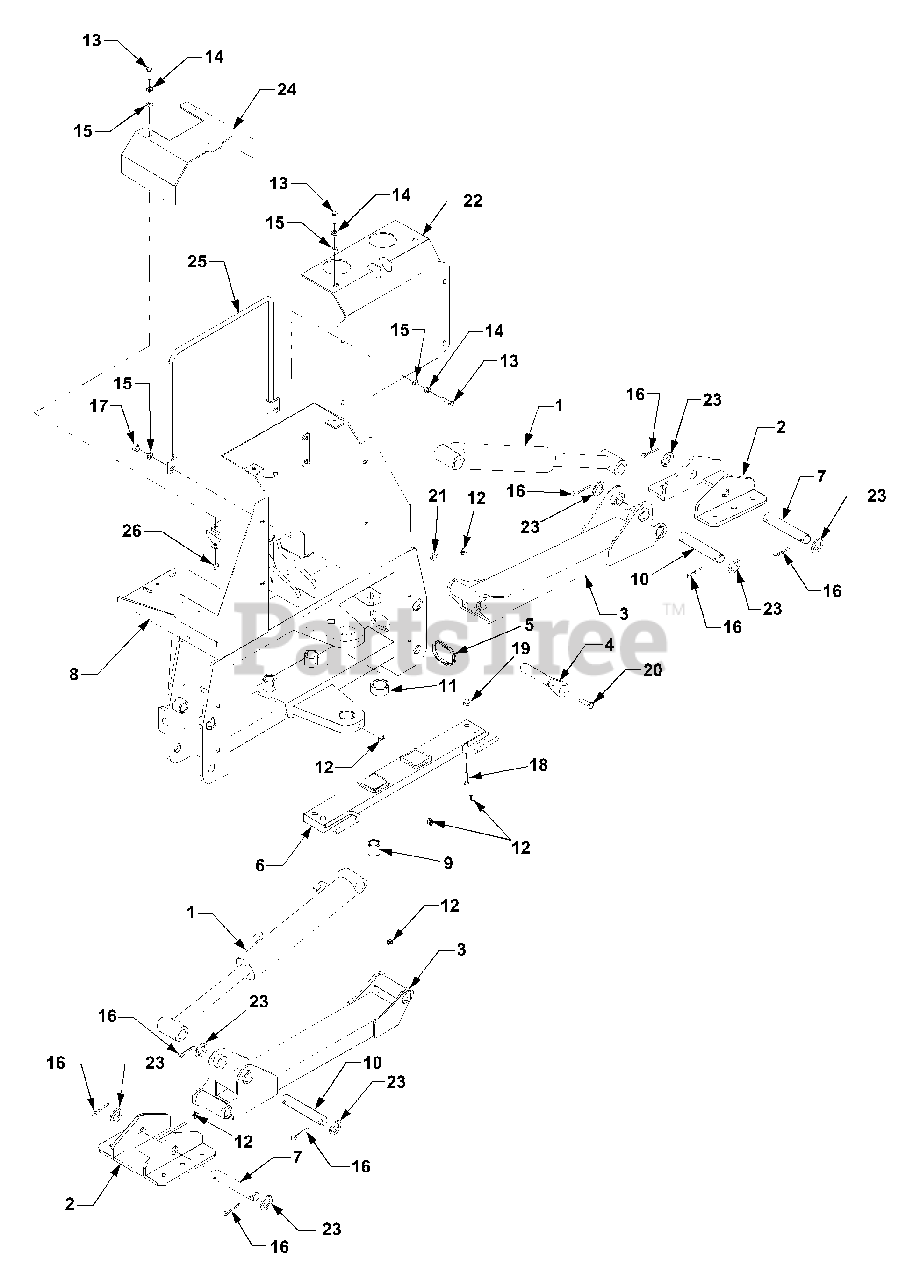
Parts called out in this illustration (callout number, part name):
1	Stabilizer Cylinder Ass'y. LH
3	Stabilizer Ass'y.
8	Mainframe Ass'y.
12	Grease Nipple
13	Hex Head Screw, M8 x 25
14	Spring Washer, M8
17	Hex Nut, M8 Lock
18	Hex Head Screw, M16 x 60
19	Hex Nut, M16 Lock
20	Hex Head Screw, M10 x 25
21	Hex Nut, M10 Lock
24	Bracket Cover
